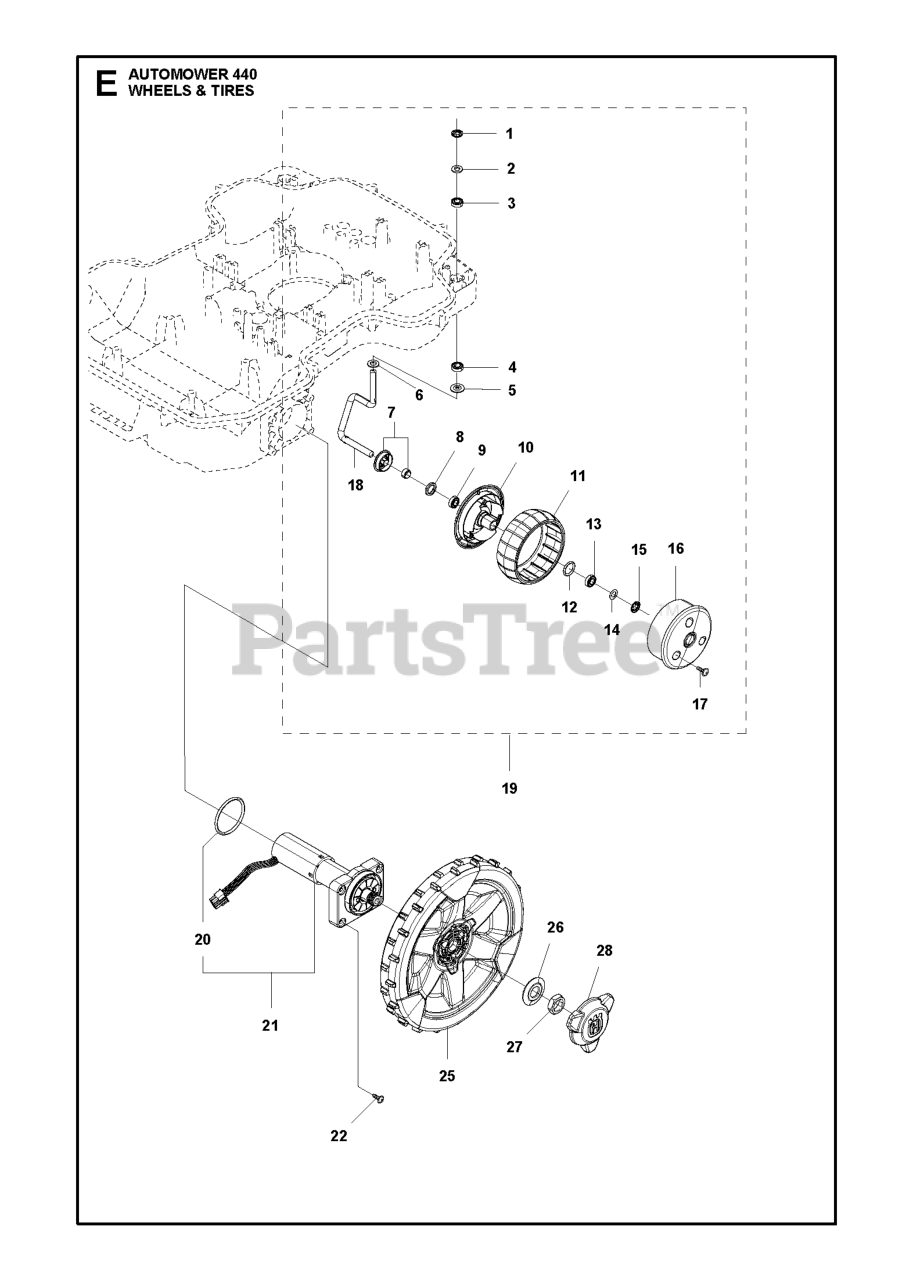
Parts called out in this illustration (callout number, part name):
1	LOCKWASHER PUSH-ON TYPE P 8 BV
2	WASHER DIN 988 13X8X0.5
3	BALL BEARING SINGLE ROW S688
4	BALL BEARING SINGLE ROW S688
5	WASHER FRONT WHEEL CENTER HOLE
6	WASHER DIN 988 13X8X0.5
7	SHIELD KIT
8	SEALING 12X18X3
9	BALL BEARING SINGLE ROW S688
10	WHEEL FRONT WHEEL INSIDE
11	WHEEL RUBBER TYRE
12	O-RING 2,62X15,54
13	BALL BEARING SINGLE ROW S688
14	WASHER DIN 988 13X8X0.5
15	LOCKWASHER PUSH-ON TYPE P 8 BV
16	WHEEL FRONT WHEEL OUTSIDE
17	SCREW 14MM
18	SPINDLE SPINDLE FRONT WHEEL RI
19	WHEEL KIT FRONT
20	O-RING LIGHT GREY
22	SCREW ITXPANT
25	WHEEL ASSY D249 HVA LIGHT GREY
26	WASHER WASHER REAR WHEEL 16X40
27	HEXAGON THIN NUT
28	HUB CAP REAR WHEEL NO CENTER P
